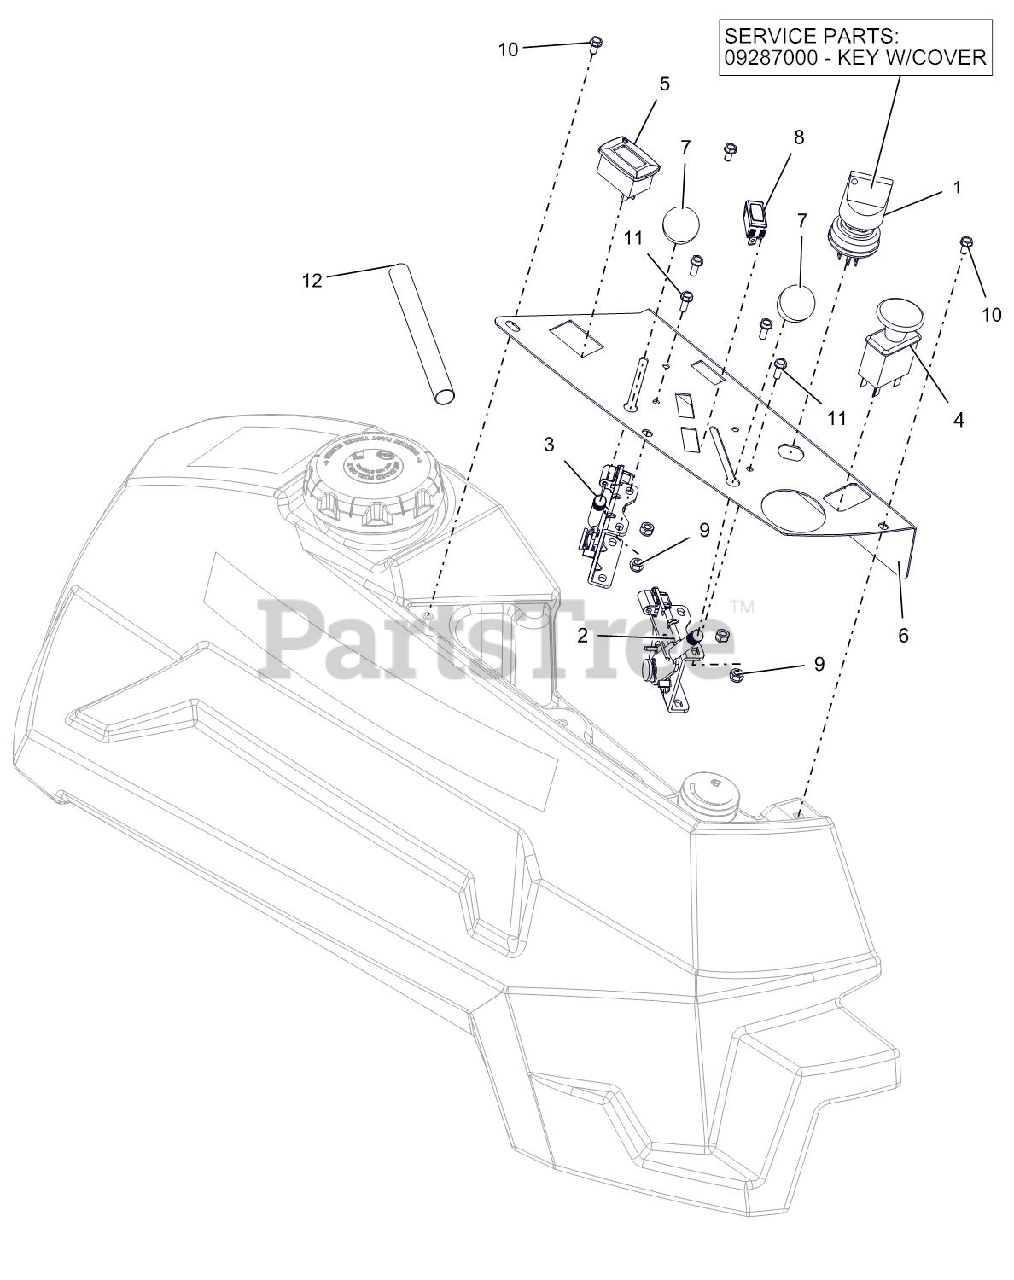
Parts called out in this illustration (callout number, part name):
1	KEY, W/ SHIELD
1	SWITCH, IGNITION
2	CABLE, PRO-CTRL 43.00"
3	CABLE, PRO-CTRL 46.00"
4	SWITCH, CLUTCH
5	METER, HOUR W/MAINTENANCE
6	PT400 CONTROL PANEL - RED
7	KNOB-CONTROL-BLACK .38-16X.50
8	LIGHT,INDICATOR
9	@NUT-LK-NYL 10-24 W/INSRT YWZC
10	SCR-MCH 10-24X.38 HWHSTAINLESS
11	@SCR-MCH 10-24X.50 HWH YWZC
12	SLEEVE, THERMAL 6"
